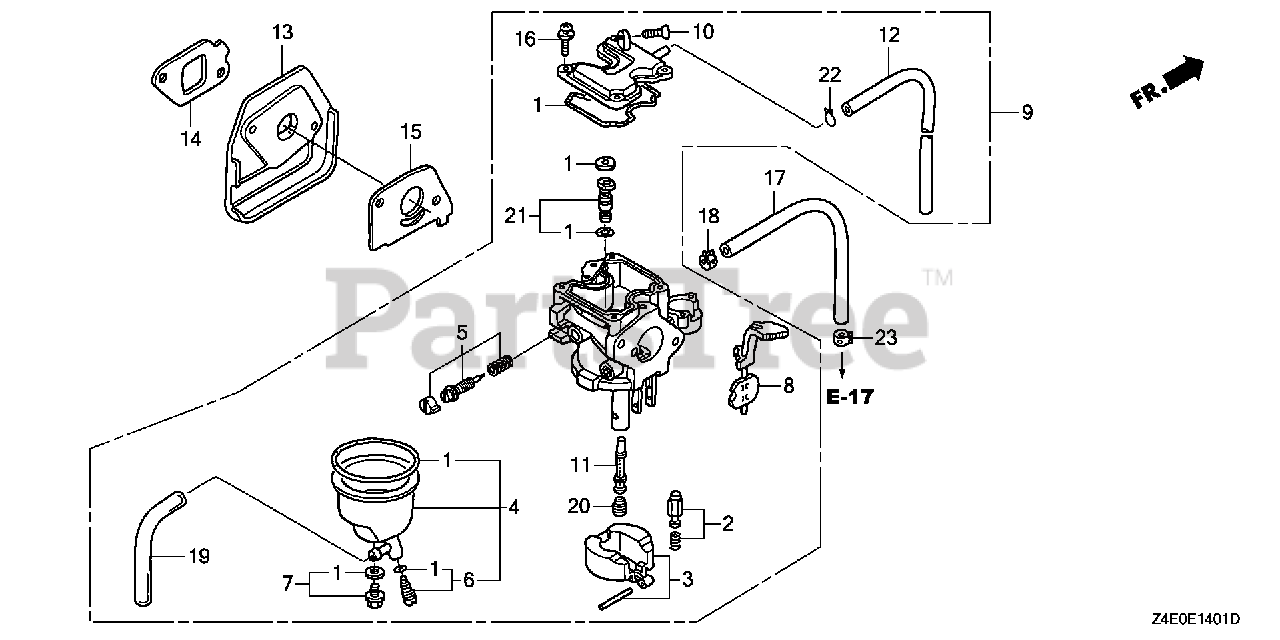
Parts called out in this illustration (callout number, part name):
1	GASKET SET (CARBURETOR NO.)
2	VALVE SET, FLOAT (CARBURETOR NO.) (SEAT NOT INCLUDED)
4	CHAMBER SET, FLOAT (CARBURETOR NO.)
6	SCREW SET, DRAIN (CARBURETOR NO.)
7	SCREW SET (CARBURETOR NO.)
8	LEVER SET, CHOKE
9	CARBURETOR ASSY. (BF33D C)
9	CARBURETOR ASSY. (BF33P A)
10	SCREW, THROTTLE STOP
11	NOZZLE, MAIN
12	TUBE, AIR VENT
13	INSULATOR, CARBURETOR
14	GASKET, INSULATOR
15	GASKET, CARBURETOR
16	SCREW-WASHER (4X12)
17	HOSE, FUEL (4.5X50) (FKM)
17	BULK HOSE, FUEL (4.5X3000) (4.5X120)
18	CLIP, TUBE (D8.5)
19	BULK HOSE, VINYL (3.5X6.5X8000) (9500(95003-05001-60M) (CARBURETOR NO.)
20	JET, MAIN (#55) Use from Engine SN BF22B D.
20	JET, MAIN (#58) Use from Engine SN BF22B D.
20	JET, MAIN (#60)
21	JET SET, PILOT (#35)
22	CLIP, TUBE (B1 8)
23	CLIP, TUBE (D8.5)
